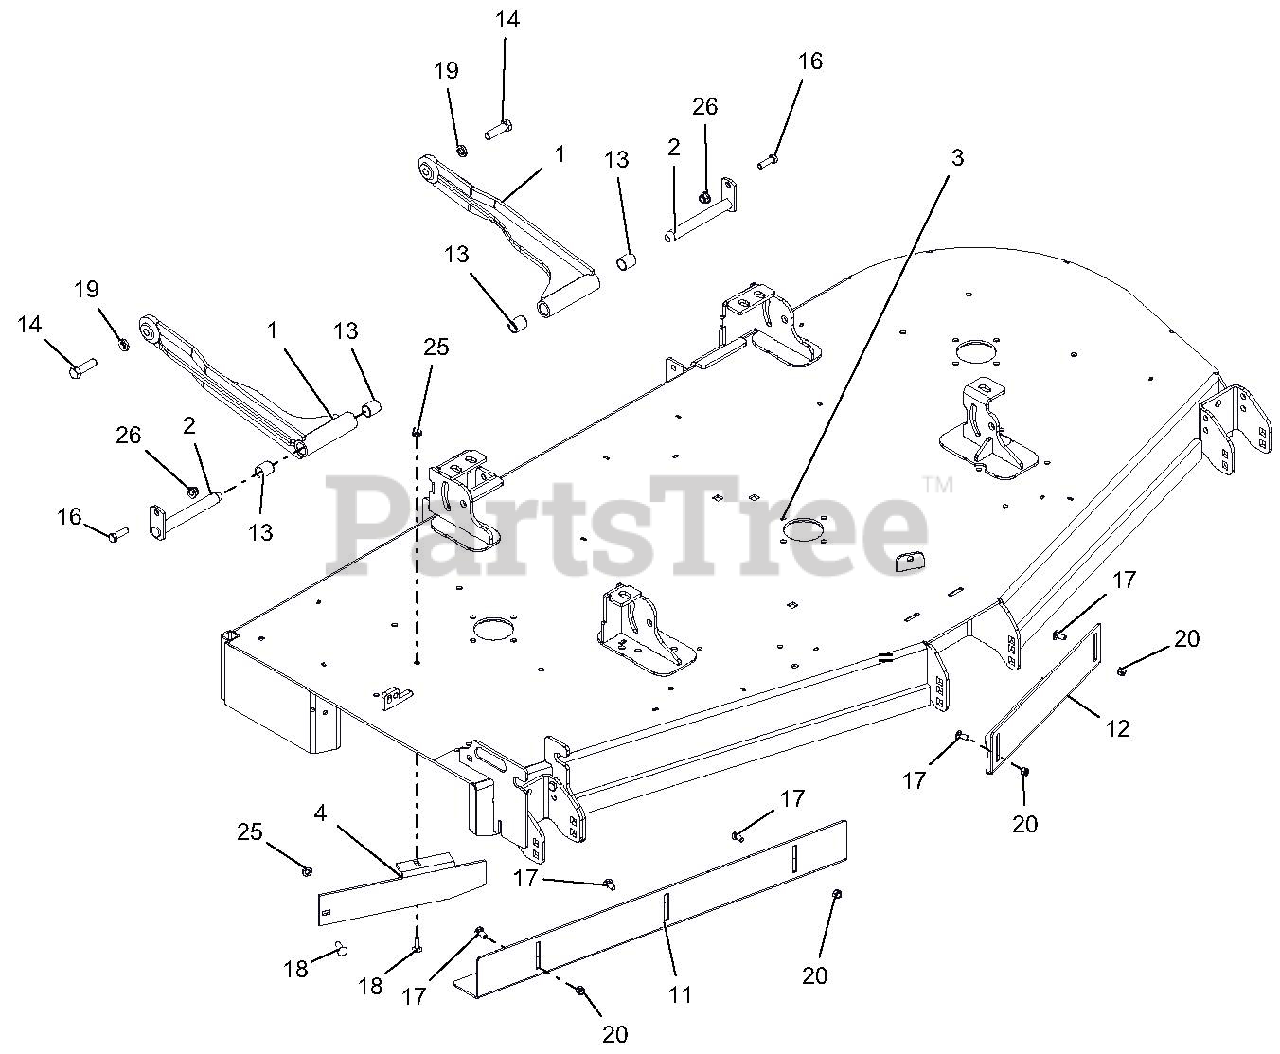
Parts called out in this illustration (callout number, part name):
1	DECK STABILIZER ARM - BLACK
2	WELDMENT, MOWER MTG. PIN
3	72" SIDE DISCH DECK W/DECALS
4	72" DISCHARGE BAFFLE - RED
11	72" RH VACUUM BAFFLE - BLK
12	72" LH VACUUM BAFFLE - BLK
13	BRG, .750 X .875 X 1.000
14	BLT-HEX .50-13X1.75 GR5EP80 YZ
16	@BLT-HEX .38-16X1.25 GR5 YWZC
17	@BLT-RDHDSQNK .31-18X.75 G5YZ
18	@BLT-RDHDSQNK .31-18X1.00 G5YZ
19	@WSHR-LK .50X.125 REG YWZC
20	@NUT-LK-NYL .312-18 YWZC
25	@NUT-LK-NYL-FLG .31-18 YWZC
26	@NUT-LK-NYL-FLG .38-16 YWZC
